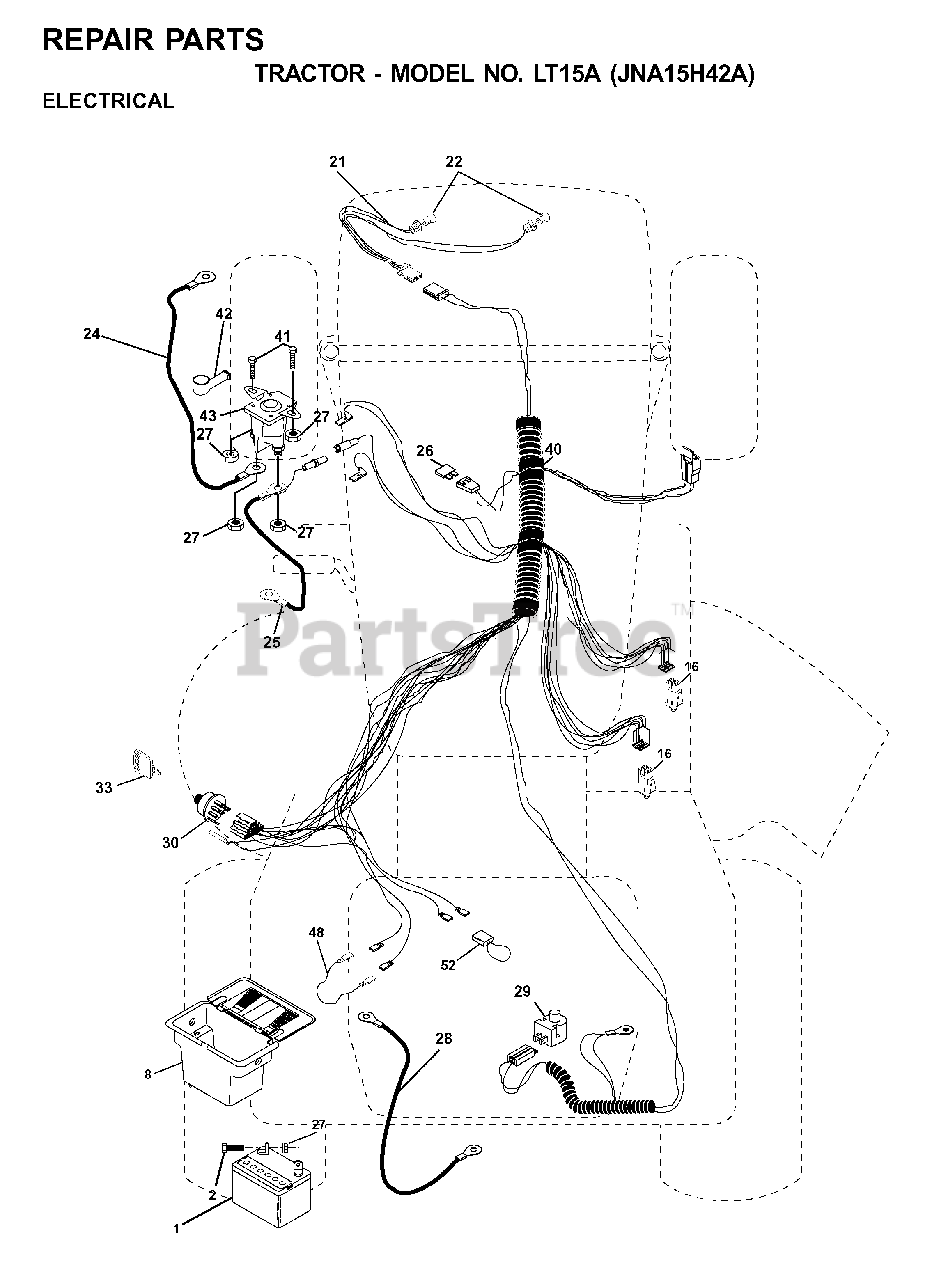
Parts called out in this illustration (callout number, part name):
1	BATTERY 12 VOLT 25 AMP
8	CASE BATTERY MECH HINGE
16	SWITCH INTERLOCK
22	LIGHTBULB
24	BATTERY CABLE GT
25	CABLE BATTERY
26	FUSE 20AMP
27	NUT
28	CABLE T
29	SWITCH SEAT
30	IGNITION SWITCH
33	KEY MLD GEN DELTA
40	HARNESS, IGN. LTH120
42	TERMINAL COVER
43	REPL BY 532 1461-54
52	WIRE PROTECTION LOOP
